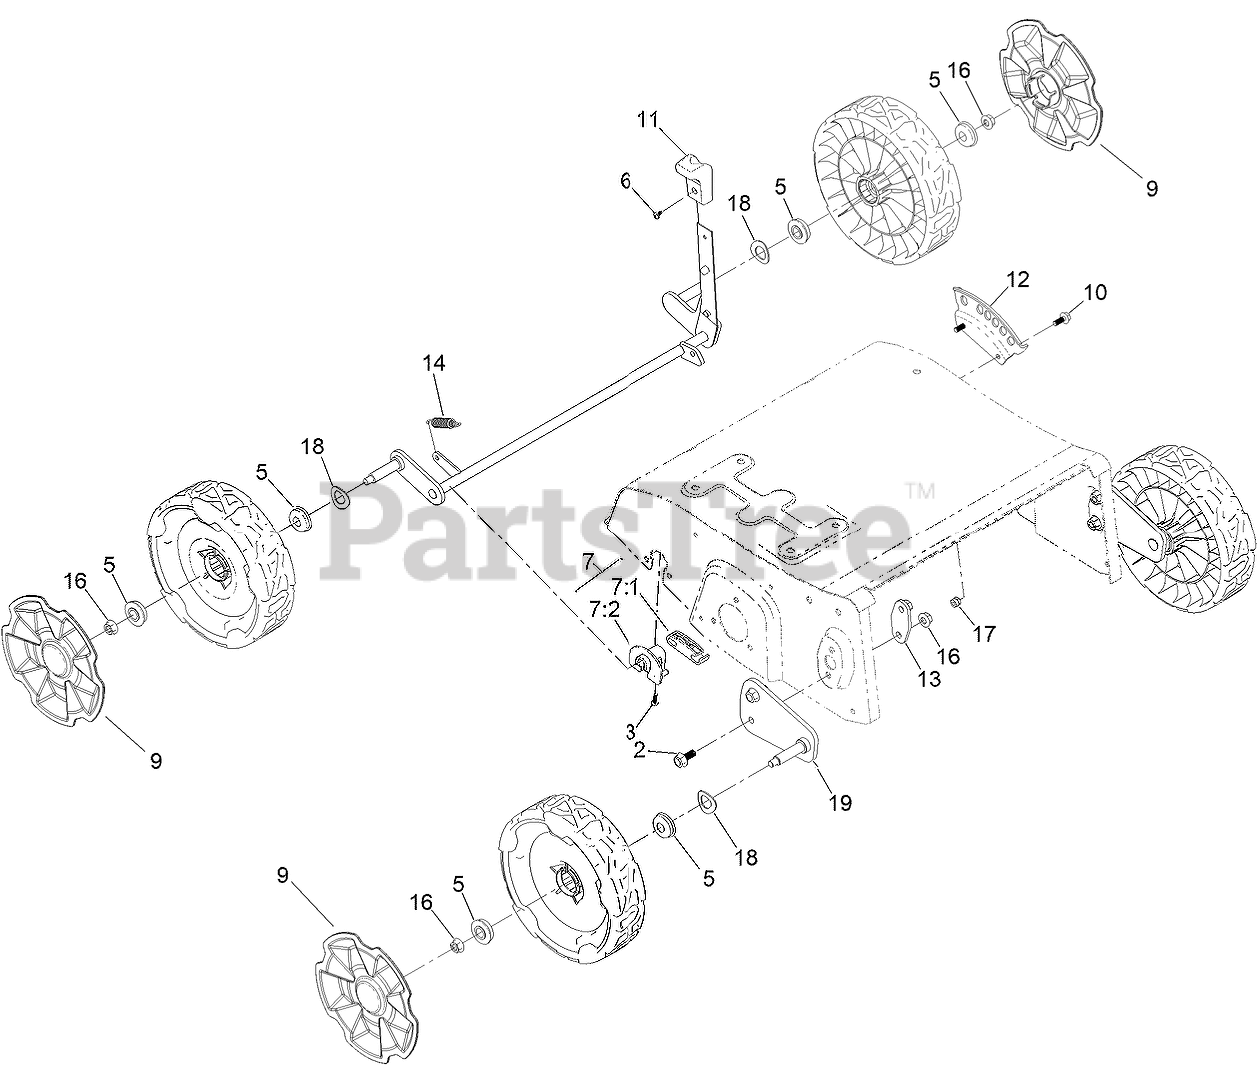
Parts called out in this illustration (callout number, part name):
2	BOLT-FLANGE, HEX
3	SCREW-CROSS RECESSED PAN HEAD
5	BEARING-STEEL
6	SCREW-PAN HEAD
7	FRONT AXLE SEAT ASSY
7:1	CLIP-AXLE
7:2	CLIP-AXLE
9	HUB CAP
10	SCREW-HHF
11	HANDLE-LEVER, HOC
12	PLATE-ADJUSTMENT, HOC
13	PLATE-AXLE, REAR
14	SPRING
16	NUT-FLANGE, HEX
17	NUT-NYLOC
18	WAVE WASHER
19	PLATE-AXLE, REAR
